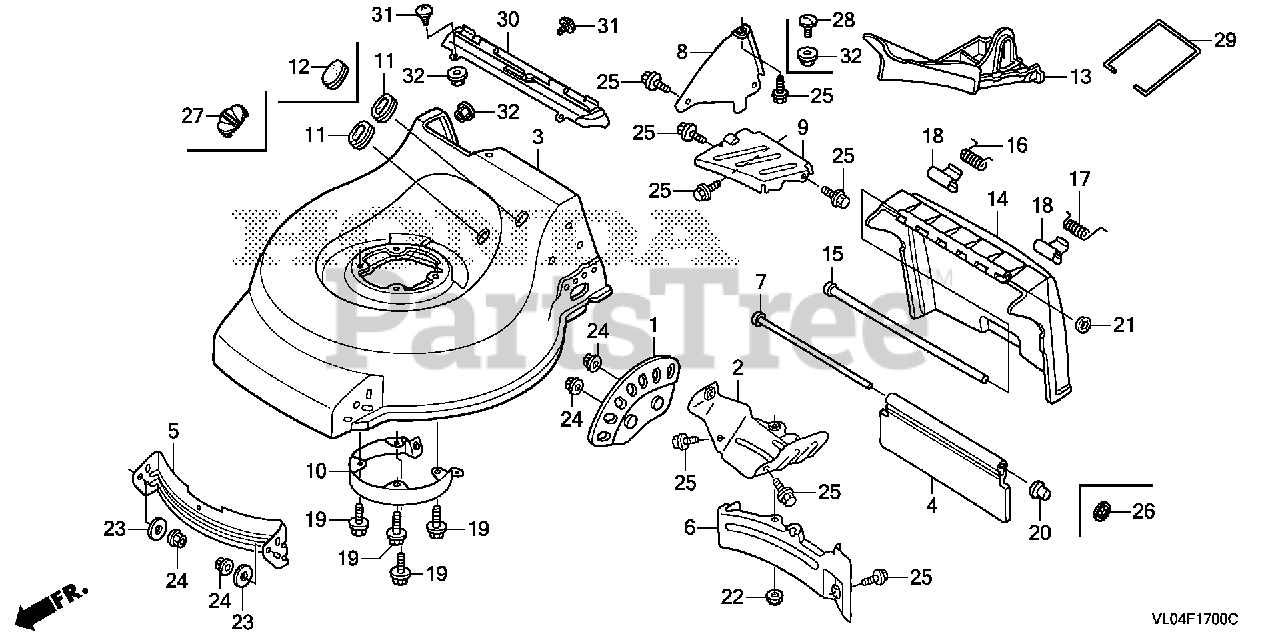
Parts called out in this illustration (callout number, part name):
2	COVER, BELT
3	HOUSING, CUTTER *NHB37M* (ROSE CHAMPAGNE LIGHT METALLIC)
4	SHIELD, RR.
5	SCROLL, FR.
6	SCROLL, RR.
7	SHAFT, RR. SHIELD (405MM)
8	PLATE, SCROLL
9	PLATE, GUIDE
10	COVER, ROTO-STOP
11	GROMMET, CABLE (HOLE)
12	GROMMET, PLUG
13	STUFFING *NH105* (MAT BLACK)
14	GUARD, DISCHARGE *NH105* (MAT BLACK)
15	SHAFT, DISCHARGE GUARD
16	SPRING, R. GUARD RETURN
17	SPRING, L. GUARD RETURN
19	BOLT, FLANGE (5/16-24X1")
21	NUT, PUSH (7.94MM)
22	NUT, NYLON LOCK (6MM)
23	WASHER, PLAIN (5/16)
24	NUT, FLANGE (8MM)
25	BOLT, FLANGE (6X10)
26	NUT, PUSH (3.96MM) (FLAT ROUND TYPE)
28	BOLT, PAN (6X12)
29	STOPPER, STUFFING
30	PLATE, GRASS BAG
31	BOLT, GRASS BAG PLATE
32	NUT, FLANGE (6MM)
